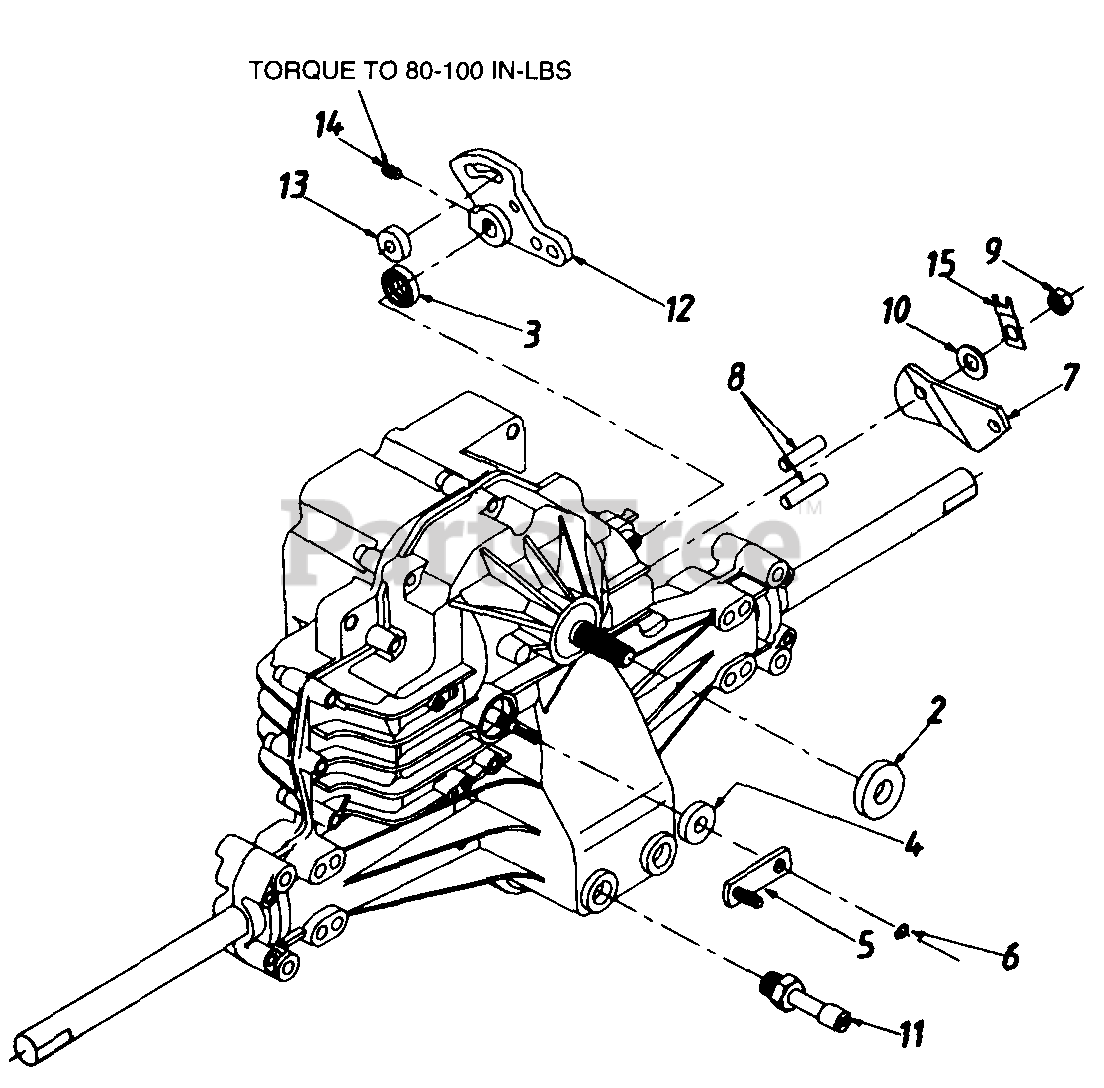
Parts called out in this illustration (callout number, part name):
2	1
3	1
4	1
5	1
6	1
7	1
8	2
9	1
10	1
11	1
12	1
13	1
14	1
15	1
